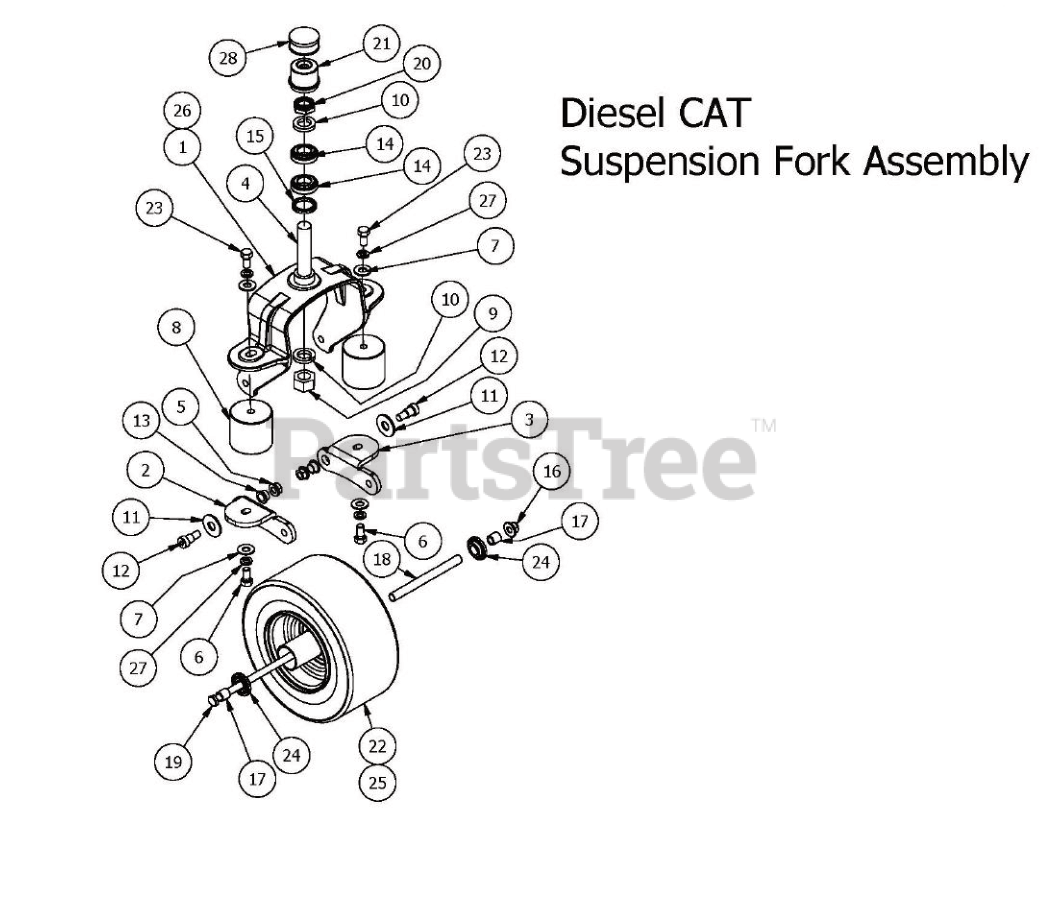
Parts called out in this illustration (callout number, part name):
1	Suspension Fork Top/Side Combo
2	Suspension Fork - Bottom Left
3	Suspension Fork - Bottom Right
4	Front Suspension Fork Spindle
5	1/2" Flange Nut
6	1/2" x 1" Hex Bolt
7	1/2" Washer (Grade 8)
8	Vibration Mount- Red Dot
9	1" Fine Thread Nut
10	1" Lock Washer
11	5/8" Flat Washer
12	5/8" x 5/8" Shoulder Bolt
13	Bronze Bushing - SF-2024-8
16	1/2-13 Nylon Flange Nut
17	Spacer 3/4 OD x 1/2 ID x 3\4 Length
18	Front Wheel Spanner
19	1/2" x 10" Bolt
20	1" Fine Thread 1/2 Nylock Nut
21	Dust Cover
22	13 x 6.50 No-Flat Large Bore Orange front Assembly
23	1/2" x 1-1/4" Gr5 Hex Bolt (Coarse)
24	1-3/4" Bearing-Large Bore Front Rim
25	13 x 6.50 Reliance No-Flat
26	Suspension Fork Assembly
27	1/2" Lock Washer
28	Spring Cap Cover
